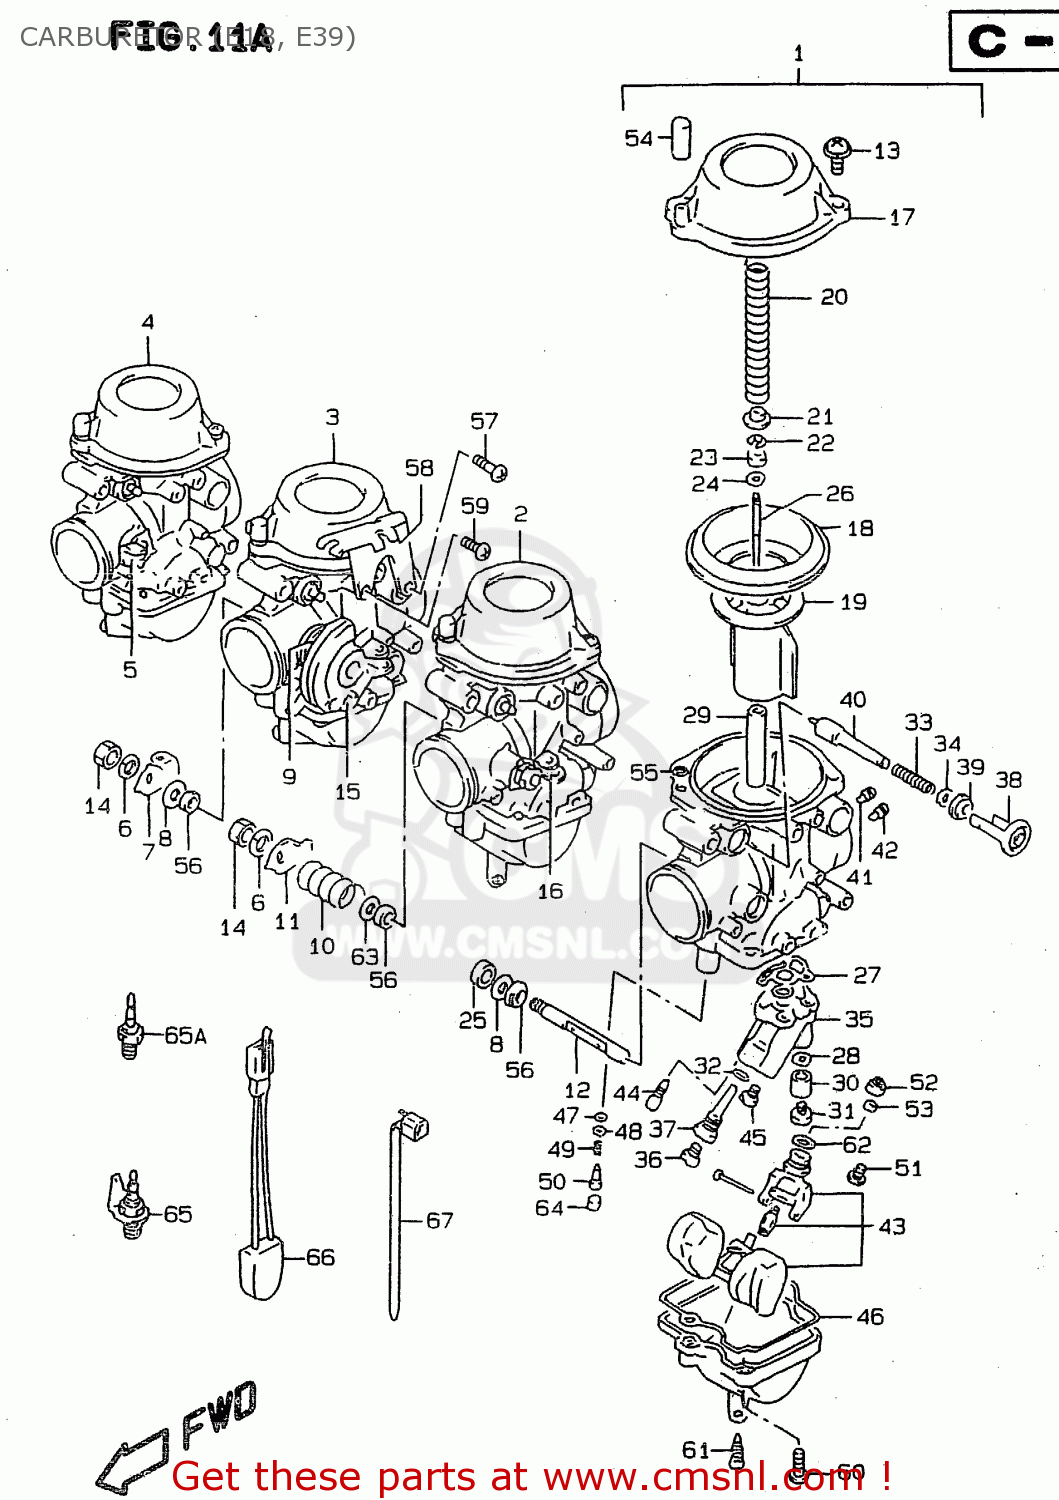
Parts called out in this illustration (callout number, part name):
1	CARBURETOR ASSY, LH
2	CARBURETOR ASSY, ML
3	CARBURETOR ASSY, MR
4	CARBURETOR ASSY, RH
5	SHAFT,THROTTLE
6	WASHER
7	LEVER,THROTTLE
8	GASKET,THROTTLE SHAFT (NAS)
9	SPRING
10	SPRING
11	SHAFT,THROTTLE
12	SHAFT,THROTTLE
13	SCREW
14	NUT
15	SHAFT,THROTTLE
16	LEVER,THROTTLE
17	COVER,DIAPHRAGM
18	DIAPHRAGM
19	VALVE,PISTON
20	SPRING
21	RING
22	E RING
23	RING
24	WASHER
25	RING
26	NEEDLE, JET (5DFT 12-3)
27	O RING
28	GASKET (NAS)
29	JET,NEEDLE(O-9)
30	RING
31	SCREW
32	O RING
33	SPRING
34	WASHER
35	JET BLOCK ASSEMBLY
36	JET,MAIN(105)
37	HOLDER,JET
38	HOLDER,GUIDE
39	CAP,STARTER
40	PLUNGER ASSY
41	JET,AIR(0.6)
42	JET,POWER(130)
43	FLOAT/NEEDLE VALVE ASSEMBLY
44	JET,PILOT(12.5)
45	JET,MAIN(52.5)
46	SEAL
47	O RING,PILOT AIR SCREW
48	WASHER
49	SPRING
50	SCREW,PILOT
51	SCREW
52	FILTER
53	RING
54	CAP
55	O RING
56	SEAL
57	SCREW(5X14)
58	BRACKET
59	SCREW
60	SCREW
61	SCREW,DRAIN
62	O-RING,NEEDLE VALVE
63	RING
64	PLUG
65	HEATER ASSY,CARBURETOR(15W)
65A	HEATER, CARB.
66	THERMO SWITCH,CARB HEATER
67	CLAMP(L:125)
